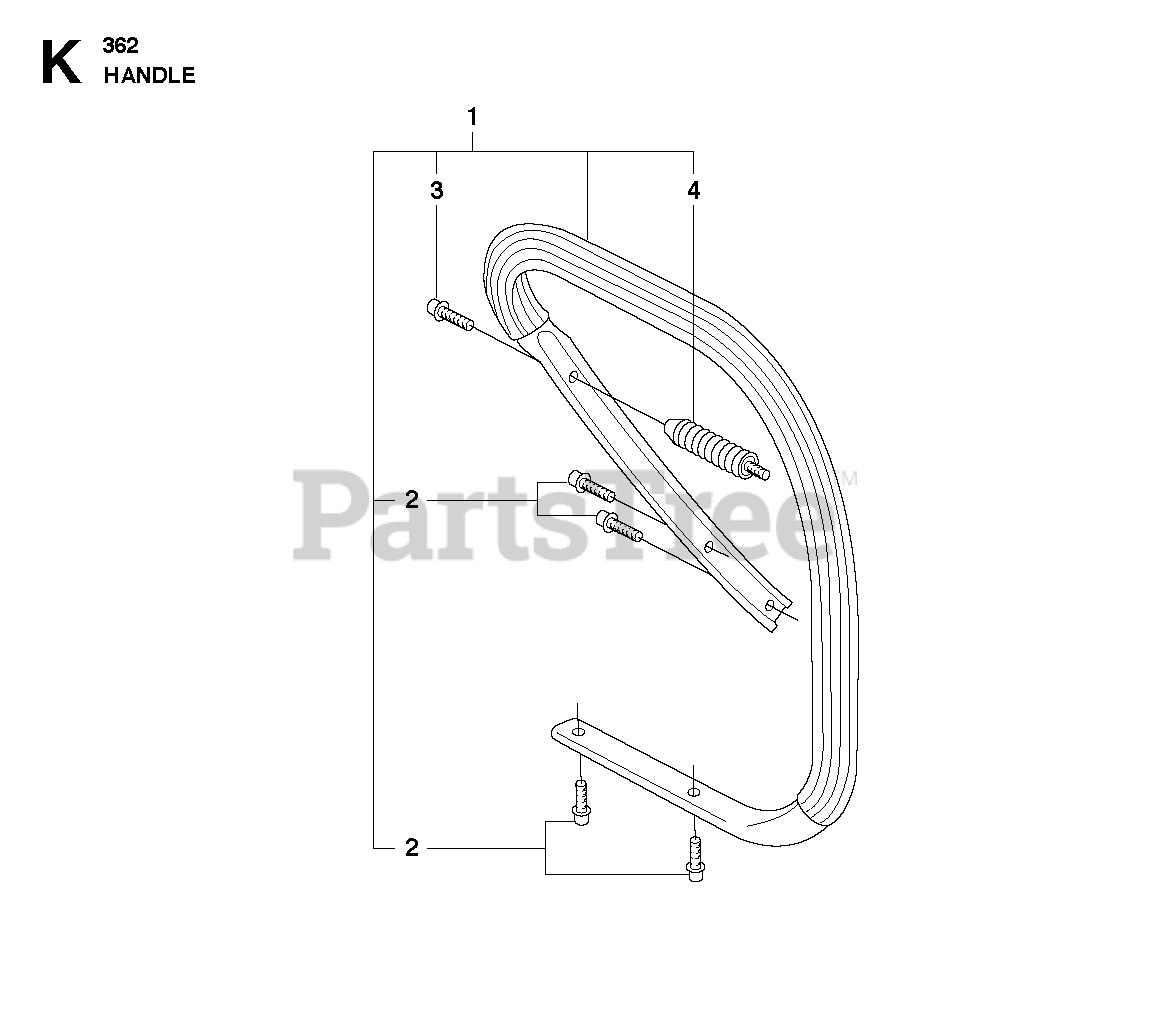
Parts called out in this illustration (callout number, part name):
1	FRONT HANDLE
2	SCREW
3	SCREW
4	ANTIVIBE MOUNT
4	VIBRATION ABSORBER
